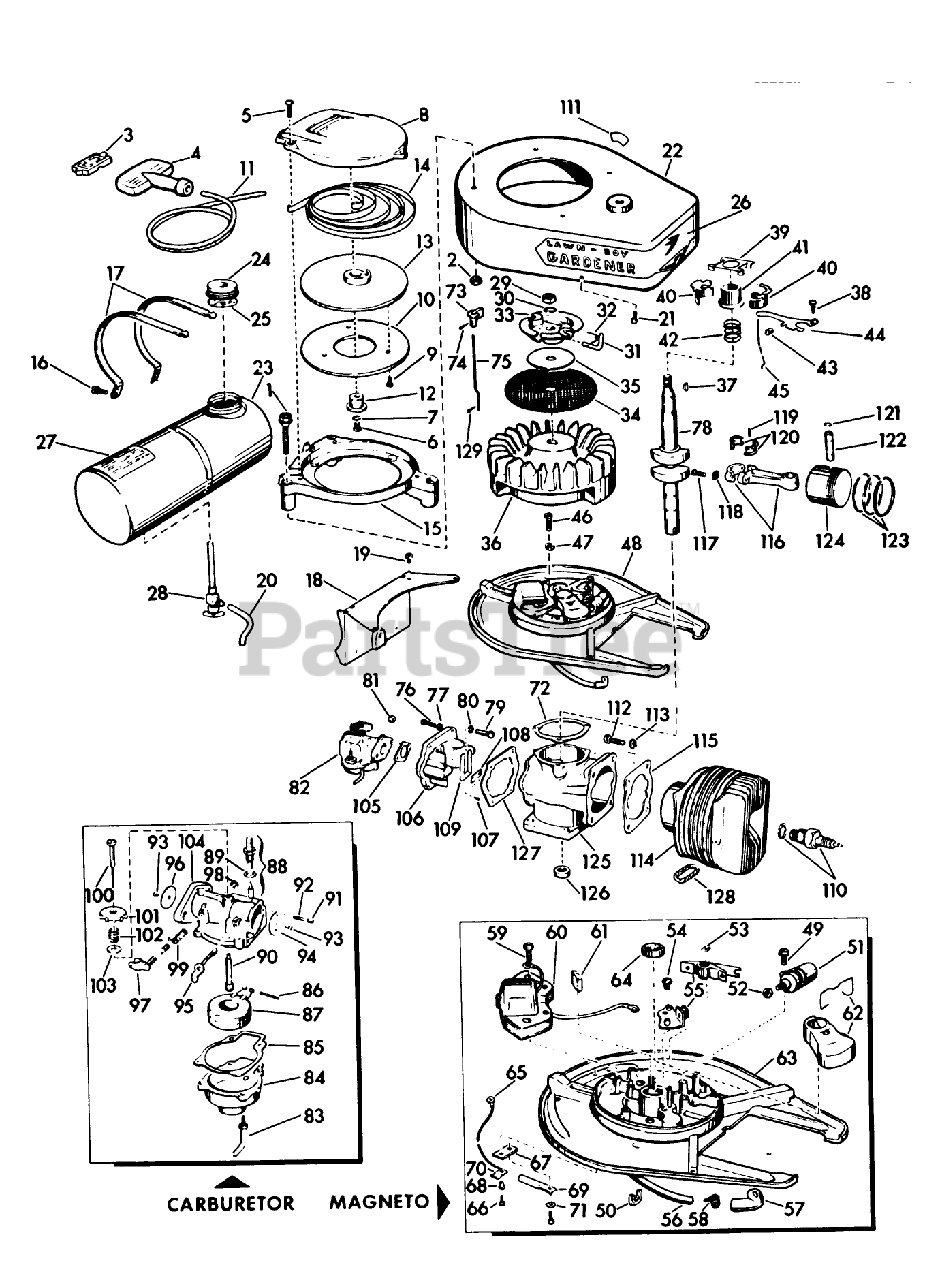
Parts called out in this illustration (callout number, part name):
10	Plate-Pulley
14	RECOIL SPRING
21	SCREW S
24	Gas Cap
27	Decal-Instruction
28	VALVE&SCREEN SM
31	PIN - STARTER
41	COLLAR S
42	Spring-Governor
43	WEAR BLOCK S
44	GOVERNER LEVER AY
45	GOVERNOR ROD S
55	BREAKER AY. S
57	Cover-Rubber
66	Screw Shut-off Switch
71	Washer, Bow
72	GASKET S
73	KNOB, CHOKE BAR
74	Cotter Pin-Choke Knob
76	SCREW S
78	Crankshaft
81	STOP NUT
93	Screw-Choke Disc
99	SPRING
100	NEEDLE AY. S
102	Spring-Ndl. Adj.
105	GASKET S
108	PLATE-BACKUP, REED
110	Spark Plug
111	Decal-Off-on
120	LINER ASM
129	Cotter Pin
